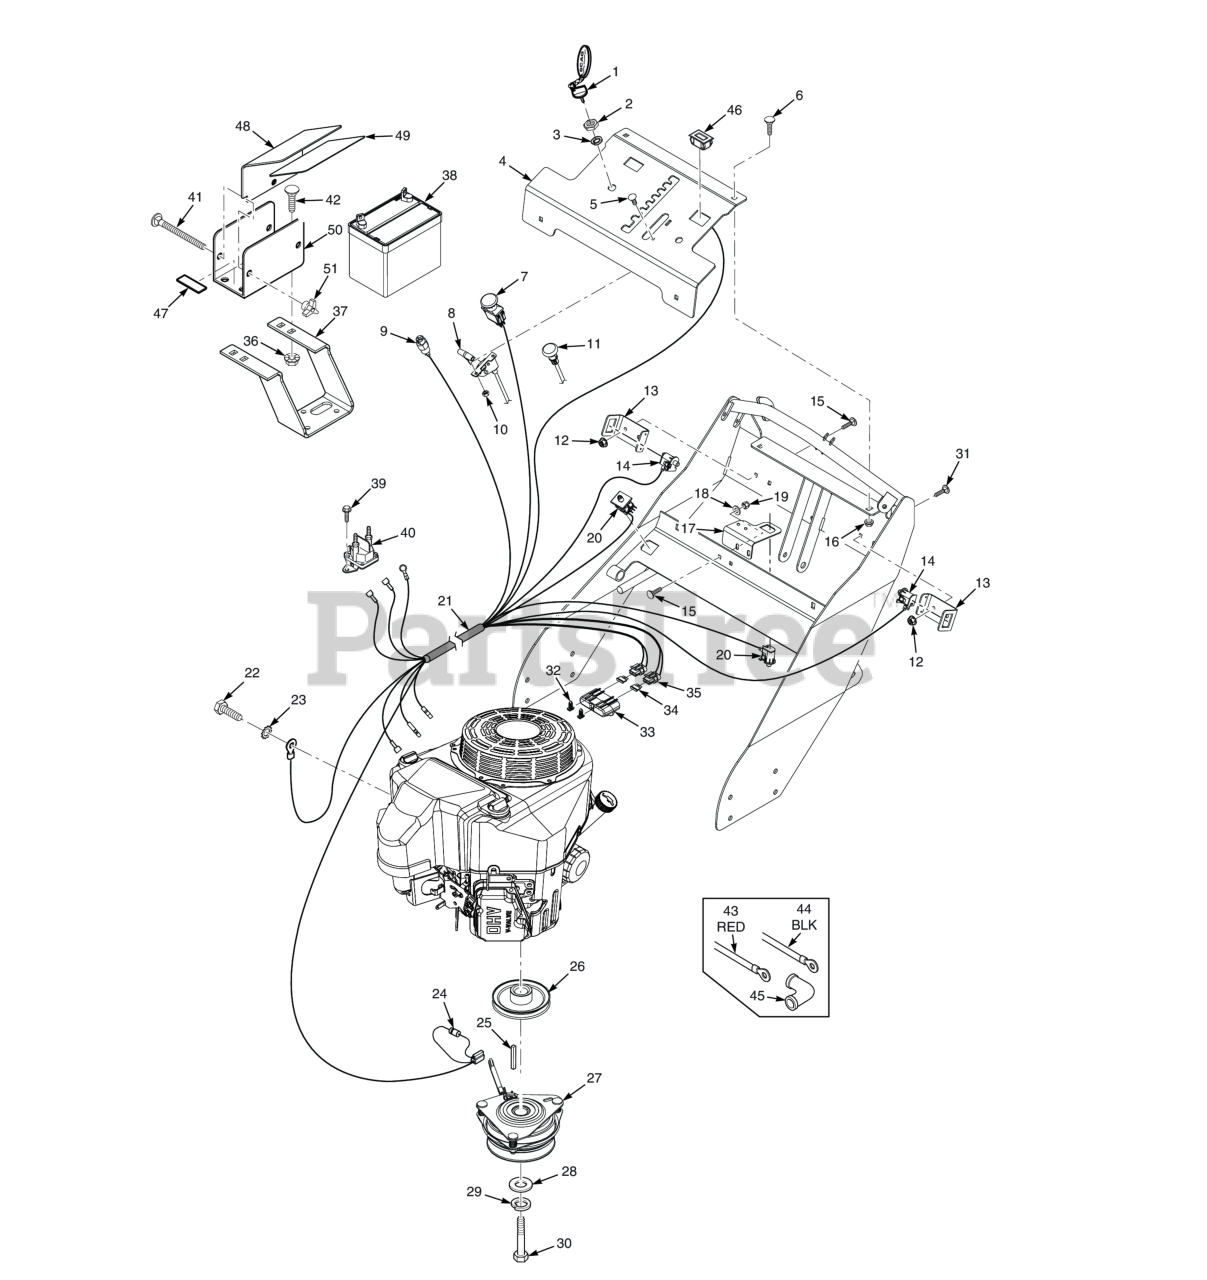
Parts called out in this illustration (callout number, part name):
1	Key, Assembly w/Fob
2	Nut, 5/8-32 Special
3	LOCK WASHER, 5/8" INTERNAL TOOTH
4	Instrument Panel w/Decal
5	Bolt, Carriage #10-24 x 1/2"
6	Bolt, 5/16-18 x .75 RHSN Carriage
7	Switch, PTO - 10 Amp
8	Throttle Cable
9	KEY SWITCH(INCLUDES MOUNTING HARDWARE)
10	Nut, Elastic Stop #10-24
11	Choke Control
12	NUT, 1/4-20 SERRATED FLANGE HEX HEAD
13	Bracket, Operator Presence Switch
14	SWITCH, NEUTRAL INTERLOCK
15	Serr. Fl. Hex Head CPSCR, 1/4-20 x 3/4"
16	Nut, Serrated Flange 5/16-18 (Right Front Engine Mounting, Briggs and Kohler Only)
17	Bracket, Neutral Switch (Electric Start Only)
18	Flatwasher, 5/16-.375 x .875 x .083 (35BV & 37BV-EFI)
19	HEX, NUT, ELASTIC STOP LOCK, 1/4-20
20	Switch, Double Pole - Plunger
21	Wire Harness
22	Bolt, Hex Hd. M8-1.25 x 14mm
23	Lockwasher, 5/16" Ext. Tooth (Kohler x1)
24	Diode, 600V 6 Amp
25	KEY, 1/4 X 1/4 X 2-1/2"
26	Pulley, 4-1/2" Dia. - 1" Bore
27	Electric Clutch Assembly
28	Flatwasher, 7/16-.469 x 1.75 x .25 (48, 52)
29	Lockwasher, 7/16� Spring
30	Bolt, Hex Head 7/16-20 x 3" w/t Patch
31	Bolt, Carriage, 1/4-20 x 1-1/4"
32	Clip, Fuse Holder
33	Cover, Sealed Double
34	FUSE, 20 AMP BLADE TYPE AUTOMOTIVE
35	Fuse Holder Assembly
36	Nut, Serrated Flange 5/16-18 (Right Front Engine Mounting, Briggs and Kohler Only)
37	Bracket, Battery Support
38	Battery, 12v - 230CCA
39	Screw, Self-Tapping 1/4-20 x 3/4
40	Solenoid, Sealed (Briggs & Stratton)
41	Bolt, Carriage 1/4-20 x 6"
42	Bolt, 5/16-18 x .75 RHSN Carriage
43	Battery Cable, Red 9" (Briggs & Stratton)
44	Cable, Battery - Black
45	RUBBER BOOT
46	Hour Meter, Inductive
47	PAD, BATTERY SUPPORT
48	Battery Box Cover
49	INSULATION, BATTERY COVER
50	Plate, Battery Box
51	ELASTIC STOP WINGNUT, 1/4-20
